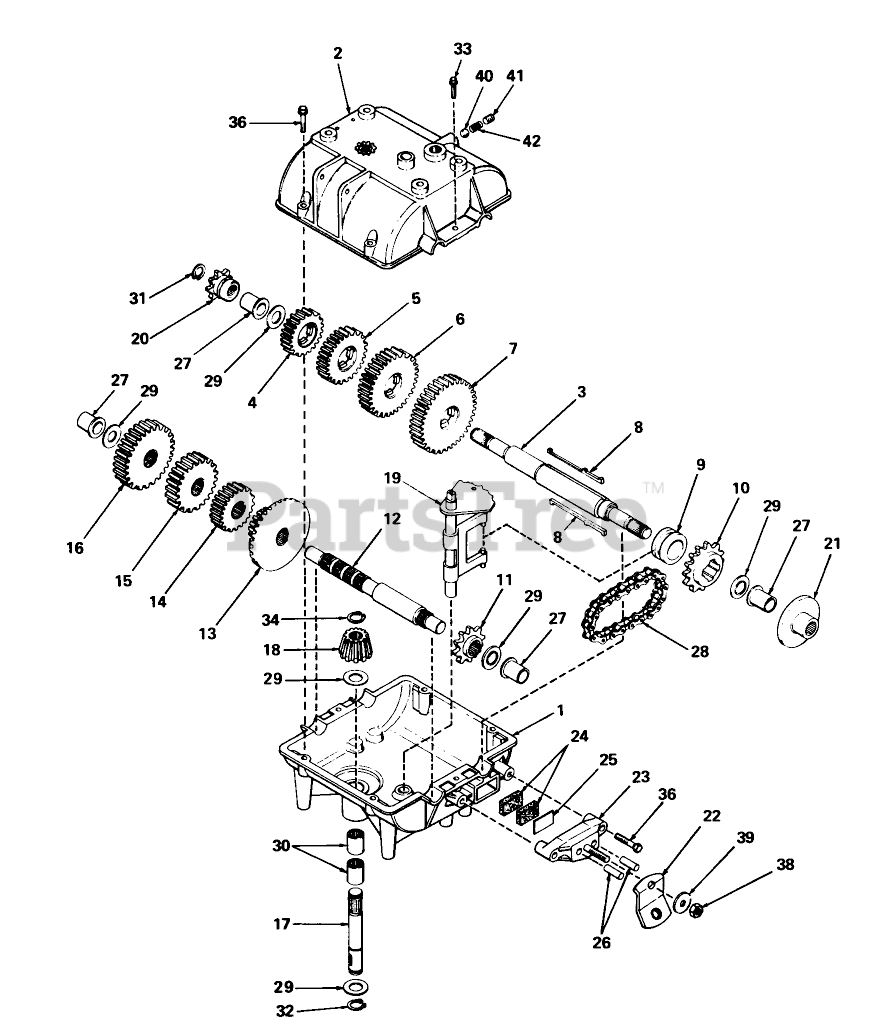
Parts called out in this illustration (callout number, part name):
1	Case-Transmission
2	Cover, Transmission
3	Shaft, Output Brake
4	Gear, Spur (20 Teeth)
5	Gear, Spur (25 Teeth)
6	Gear, Spur (30 Teeth)
7	Gear, Spur (35 Teeth)
9	Collar-Shift
10	Sprocket (14 Teeth)
11	Sprocket 10t
12	Countershaft
13	Gear-Bevel (42 tooth 15 tooth spur gear)
14	Gear, Spur (20 Teeth)
15	Gear, Spur (25 Teeth)
16	Gear, Spur (30 teeth)
17	Shaft-Input
18	Bevel Pinion, Input
19	Rod Fork Assy, Shifter
20	Sprocket (8Teeth)
22	Lever, Brake
23	Holder-Brake Pad
24	Brake Pad
25	Brake Pad Plate
26	Dowel Pin
27	Bushing, Flanged
28	Chain, Roller (#41 Chain, 22 Links)
29	Washer
30	Bearing, Needle
31	Piston Asm (.020 O S)
32	Ring-Snap
33	Screw, Hex Hd. Tap-Tite
34	Ring-Retainer
36	Ring Set (.020 O S)
38	Locknut
39	Washer
40	Ball-Steel
41	Screw-Set
42	Spring
